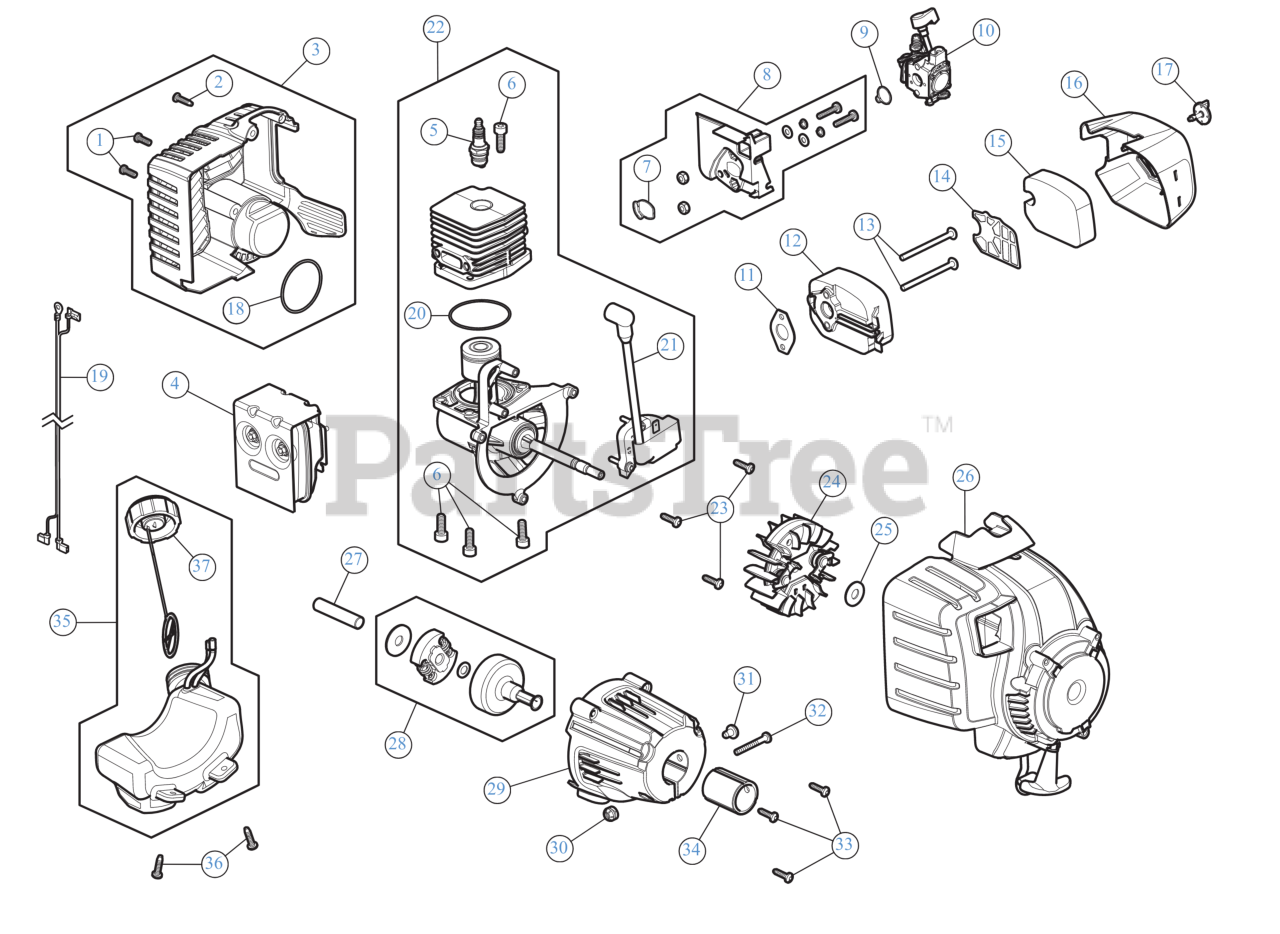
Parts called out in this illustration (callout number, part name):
1	SCREW:10-32X.562:#8P
2	SCREW, #8-16X.750 PH
3	HOUSING-ENGINE REAR
4	MUFFLER ASSEMBLY
5	SPARK PLUG
6	SCREW, 1/4-20 x .75
7	O-RING
8	INTAKE ASSEMBLY
9	O-RING
10	CARBURETOR
11	GASKET CARB
12	AIR CLEANER BASE
13	SCREW 10-32X2.5
15	FILTER
16	AIR CLEANER COVER
17	KNOB COVER
18	O-RING
19	LEAD WIRE
20	O-RING
21	MODULE
22	SHORTBLOCK
23	SCREW:10-32X.562:#8P
24	FLYWHEEL ASSEMBLY
25	BELL WASHER
26	STARTER HOUSING
27	SPACER
28	SMALL CLUTCH ASSEMBLY W/SMALL DRUM
29	CLUTCH COVER ASSEMBLY
30	HEX NUT
31	SCREW 1/4-20X3/8
32	SCREW
33	SCREW, #8-16X.750 PH
34	RUBBER SPACER
35	FUEL TANK
36	SCREW:10-6 x .75
37	FUEL CAP
